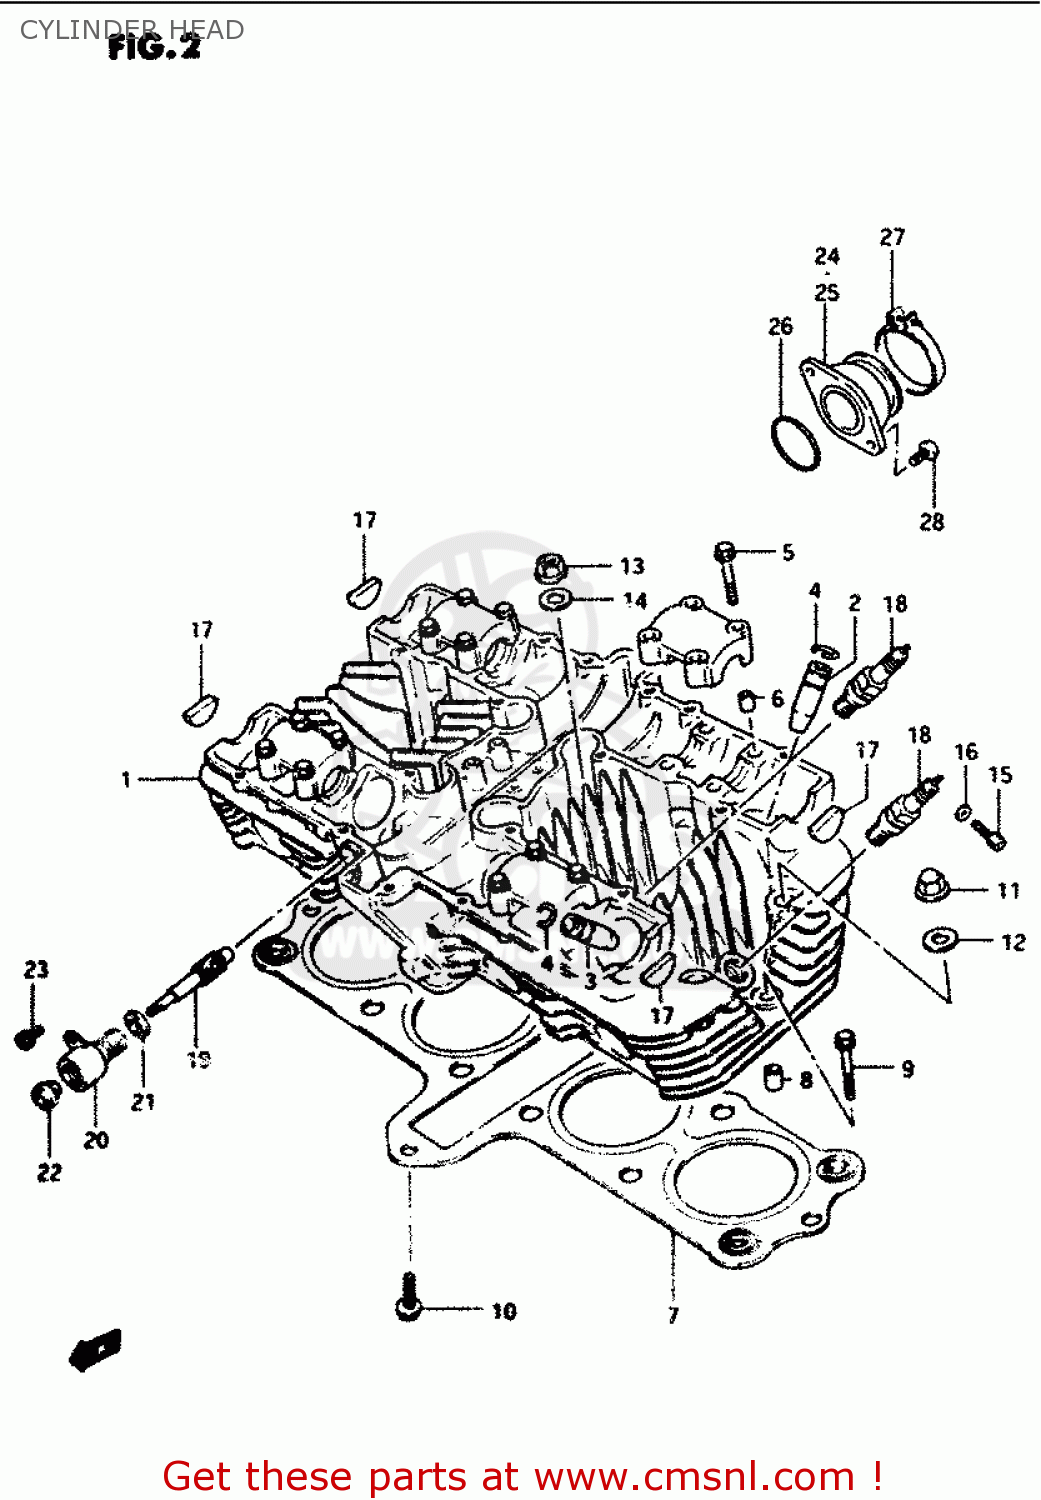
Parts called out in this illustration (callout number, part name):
1	HEAD ASSEMBLY,CYLINDER
2	GUIDE,INTAKE VALVE
3	GUIDE,EXHAUST VALVE
4	RING,SNAP
5	BOLT(6X39)
6	PIN(6.2X8X11)
7	GASKET,CYLINDER HEAD (NAS)
8	PIN
9	BOLT (6X45)
10	BOLT 6X30
11	NUT
12	GASKET(10.5X22X2) (NAS)
13	NUT
14	WASHER(10.5X22X2.3)
15	BOLT, INTAKE PORT
16	GASKET(5.3X9.3X1.2) (NAS)
17	PLUG
18	PLUG,SPARK
19	GEAR,TACHOMETER DRIVEN
20	SLEEVE,TACHOMETER DRIVE GEAR
21	SEAL,TACHOMETER DRIVEN
22	SEAL,OIL(5X12X8)
23	SCREW(5X12)
24	PIPE,INTAKE,R
25	PIPE,INTAKE,L
26	O-RING (D:2.4 ID:39.7)
27	CLAMP
28	SCREW
